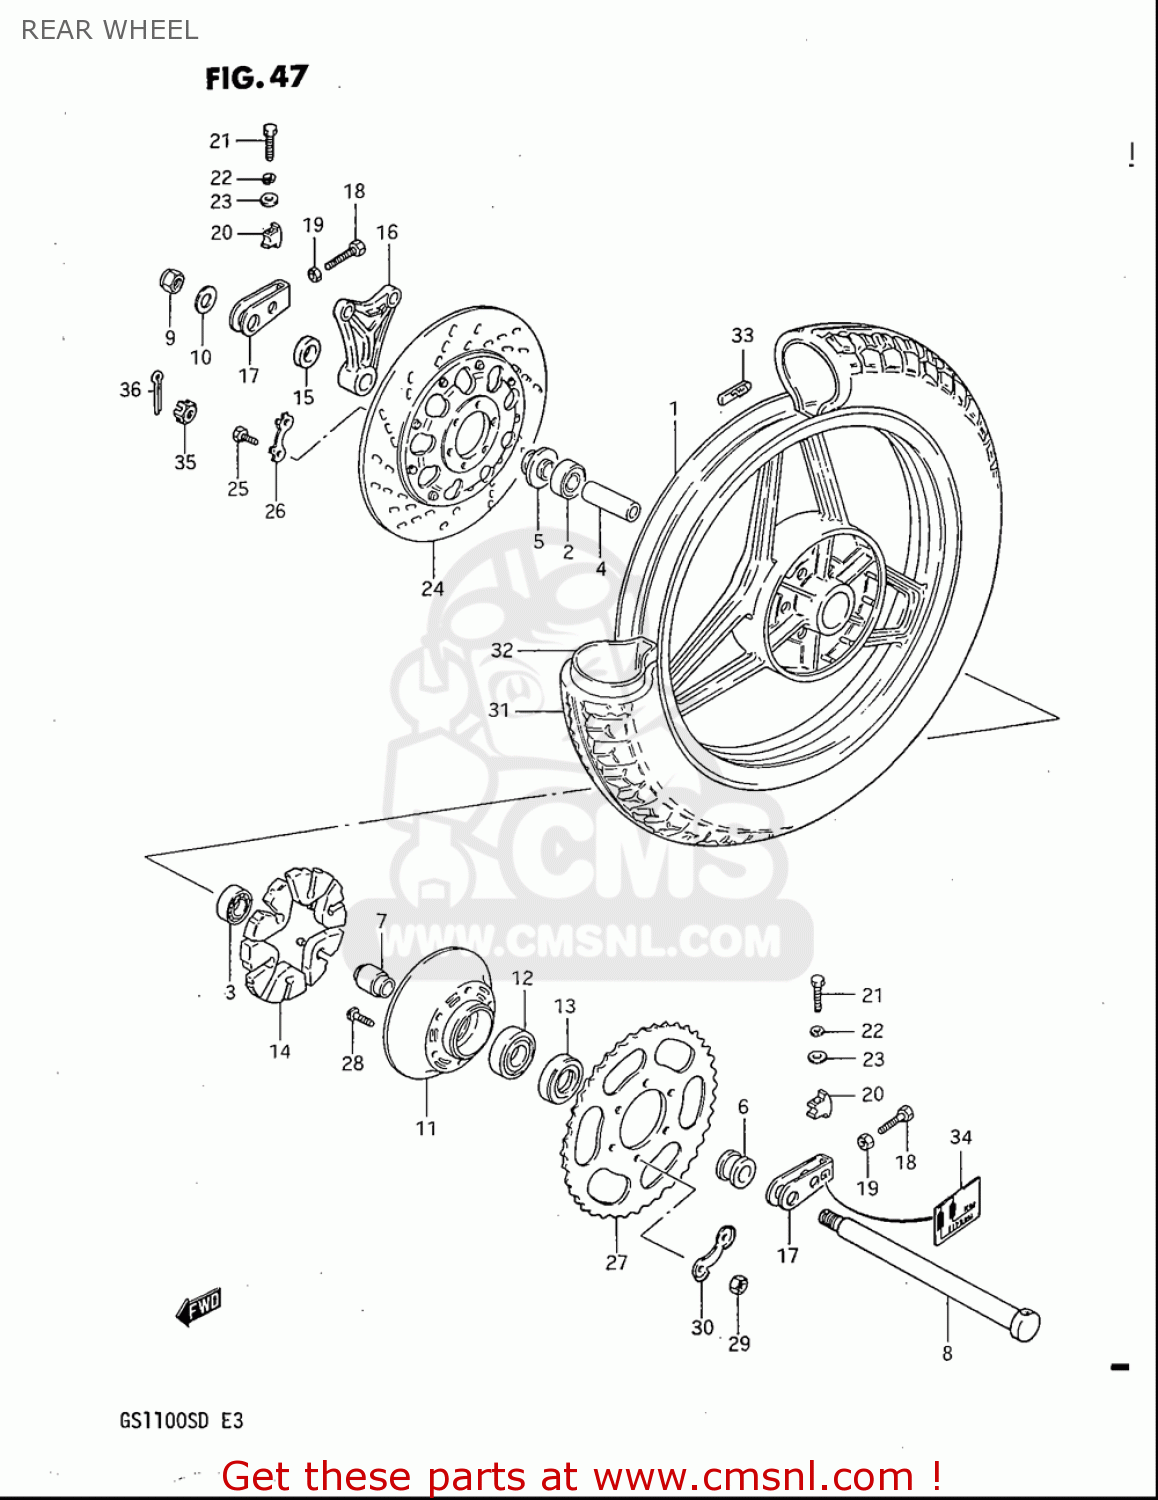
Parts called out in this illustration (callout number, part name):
2	BEARING WHEEL REAR(20X47X14)
3	BEARING(20X47X14)
4	SPACER(20.5X28X88)
5	SPACER,RR AXLE,R
6	SPACER(20X33X28.3)
7	SPACER,REAR HUB BEARING
8	AXLE,REAR
9	NUT
10	WASHER(19X34X4)
11	DRUM,RR SPROCKET MOUNTING
12	BEARING(25X62X17)
13	SEAL,OIL(33X62X7)
14	ABSORBER,RR HUB SHOCK
15	SPACER(20X38X12)
16	BRACKET,RR,CALIPER
17	ADJUSTER,CHAIN
18	BOLT(8X50)
19	NUT
20	SUPPORTER,CHAIN ADJUST
21	BOLT
22	WASHER,LOCK
23	WASHER
24	DISC,RR BRAKE
25	BOLT(8X30)
26	WASHER
27	SPROCKET,RR(NT:42)
28	BOLT(10X35.5)
29	NUT
30	WASHER
31	TIRE 4.50V17
32	TUBE ASSY,WHEEL INNER
33	BALANCER,WHEEL(20G)
34	LABEL,CHAIN WEAR INDICATOR
35	NUT 18MM
36	PIN
